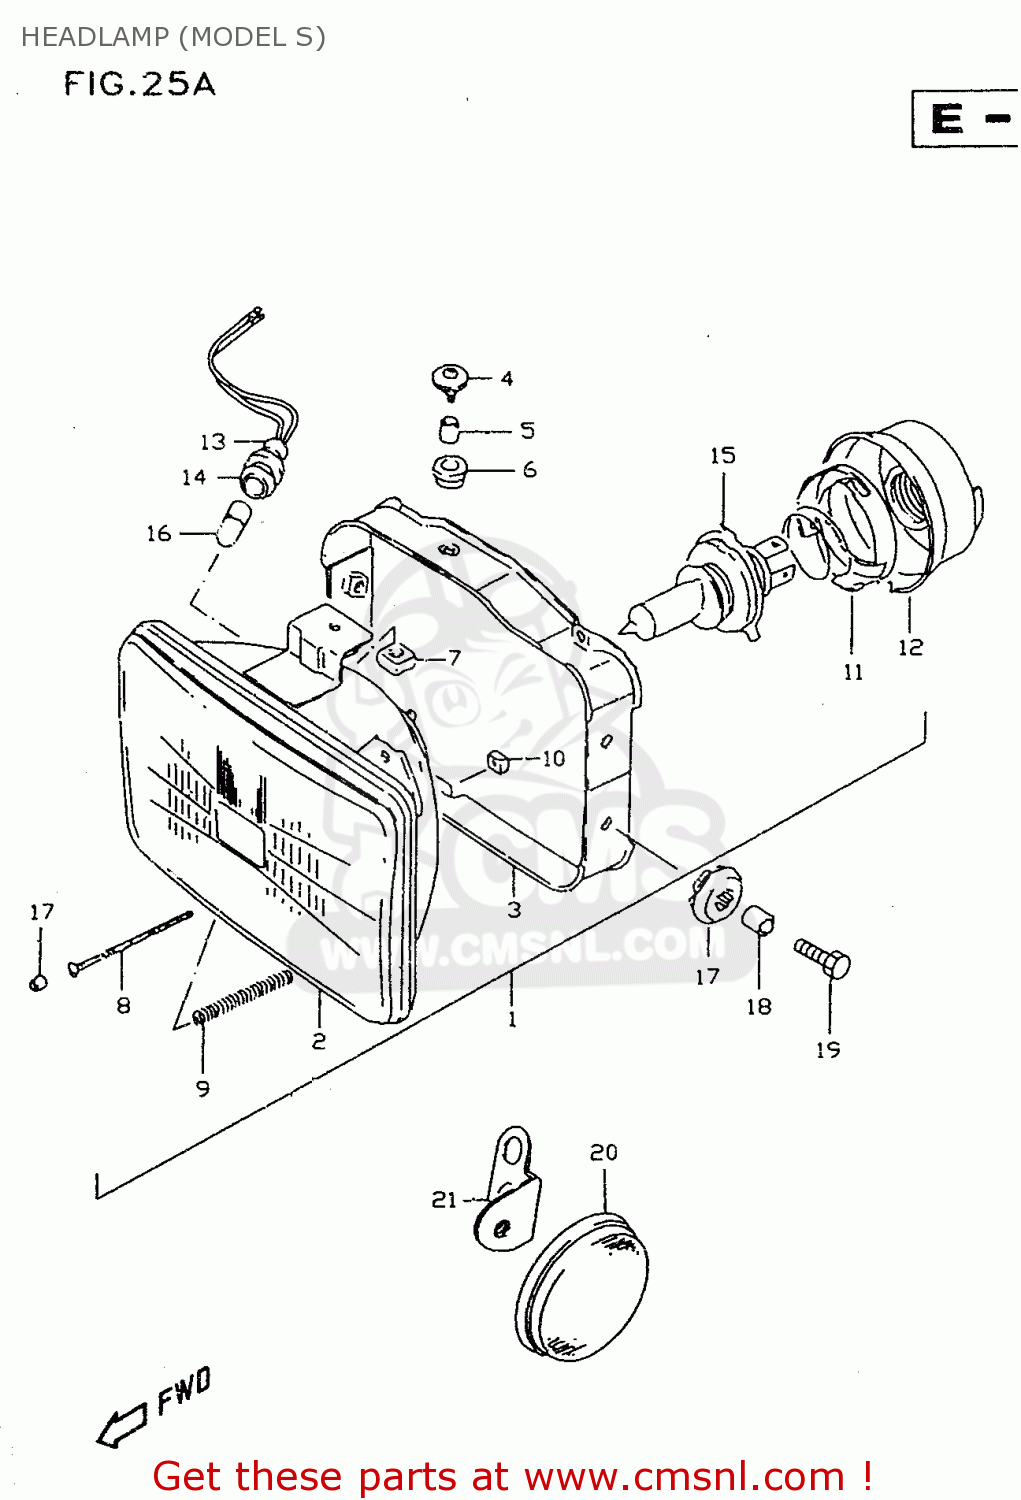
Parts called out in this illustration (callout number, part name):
1	HEADLAMP ASSY
2	LAMP UNIT
3	HOUSING
4	SCREW,MOUNTING
5	SPACER
6	CUSHION
7	NUT
8	SCREW
9	SPRING
10	NUT
11	HOLDER,BULB
12	COVER,SOCKET
13	SOCKET
14	JOINT,RUBBER
15	BULB(12V60/55W,H4)
16	BULB(12V4W)
17	CUSHION
18	SPACER(6.3X9.1X11.5)
19	BOLT(6X20)
20	REFLECTOR,REFLEX FR
21	BRACKET,FR SIDE REFLECTOR,L
